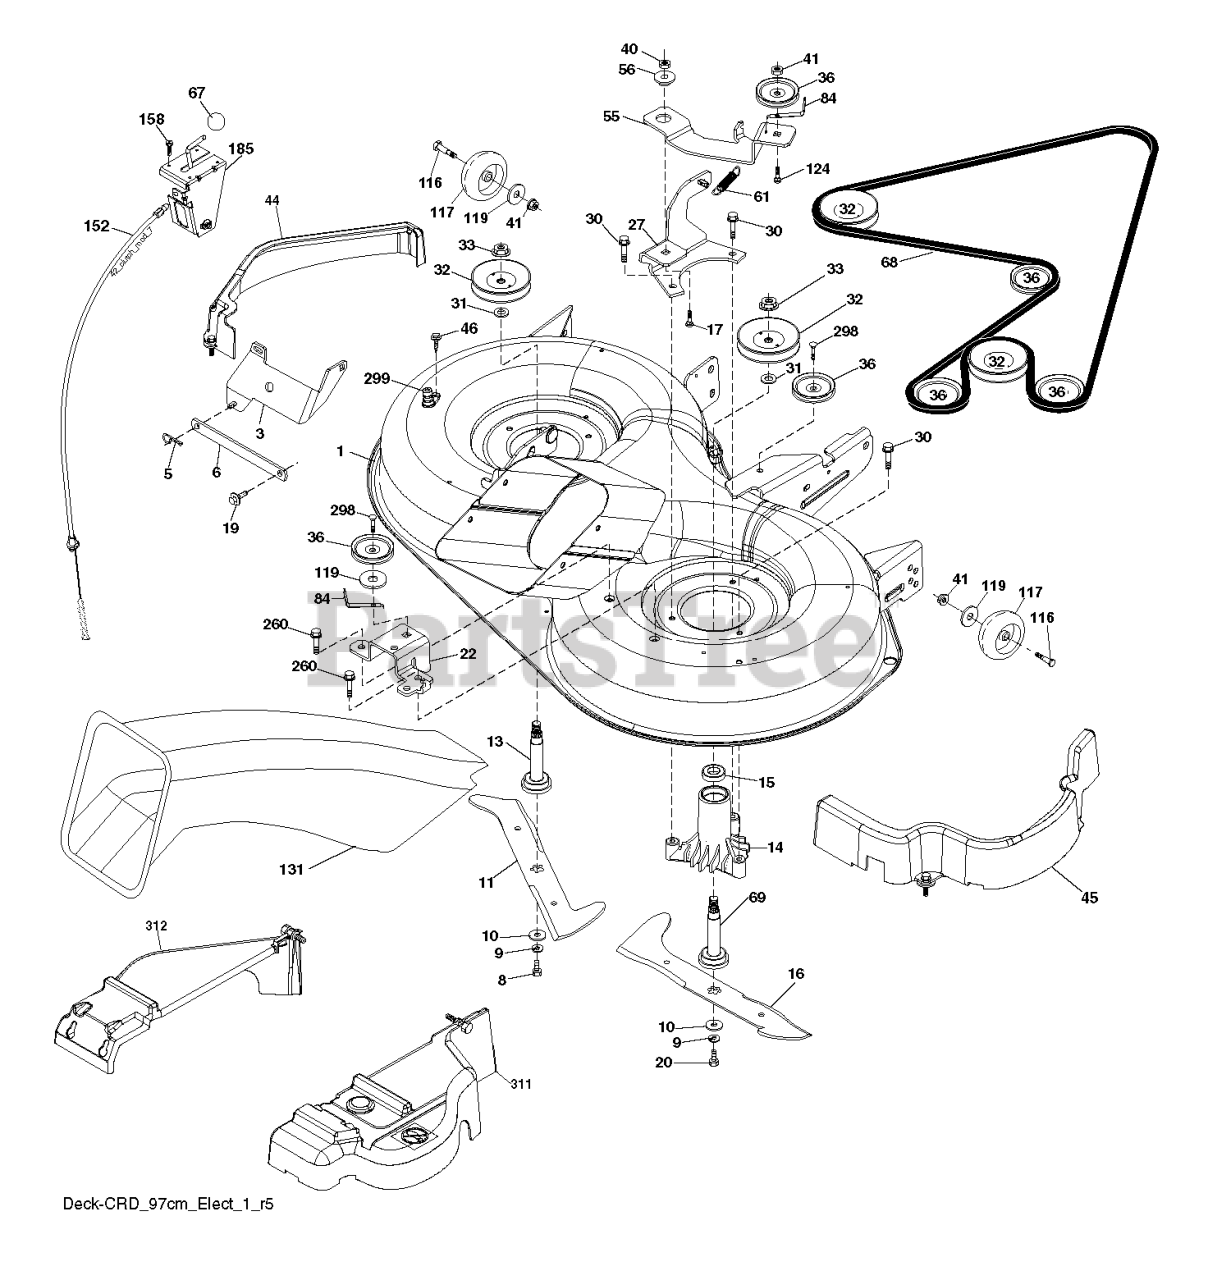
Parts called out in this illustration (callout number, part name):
1	DECK.WLDT.97.CRD.2GWB.
3	BRACKET.ASM.BAR.SWAY.CHASS
5	RETAINER-SPRNG RB
6	BAR.SWAY.92.CRD
8	BOLT.3/8-24X1.25 GR8
9	LOCKWASHER
10	WASHER.BLADE
11	BLADE.3N1.LH.CRD.97
13	SHAFT ASM VENT
14	HOUSING.MANDREL.VENTED (MACHD)
16	BLADE.3N1.RH.CRD.97
17	BOLT.3/8-14X1.25
19	BOLT SHD 5/16-18
20	BOLT.3/8-24X1.25GR8. LHTHRD
22	BRACKET.SUPT.IDLER.REAR.RH
27	BRACKET.ASM.SUSP.REAR.RH.
30	SCREW, WASHER HEAD
31	WASHER.SPACER.MANDREL
32	PULLEY MANDREL
33	NUT.FLANGE.LOCK.TOP
36	PULLEY.IDLER.4.25
41	NUT LOCK FLG 3/8-16 UNC
44	COVER MANDREL LEFT
45	COVER MANDREL RIGHT
46	SCREW.1/4-20X5/8
55	ARM.IDLER.92 CRD.2006
56	SPACER.RETAINER.MOWER
61	SPRING
67	KNOB T (3/8 HOLE)
68	BELT.DRIVE.CRD.97.2010
69	SHAFT.ASM.W/LWR.BRG.RH.THREAD
84	KEEPER, BELT IDLER
116	BOLT.SHOULDER.3/8-16X3-5/8.
117	RP WHEEL. GUAGE RALLY
119	WASHER
124	BOLT.3/8-16X1.50
131	CHUTE BAGGER
158	SCREW
185	HEAD ASM. CABLE CLUTCH
260	SCREW 3/8-16X1/2
298	SCREW LT
299	PORT.WASHOUT
311	COVER RIGHT
312	COVER LEFT
